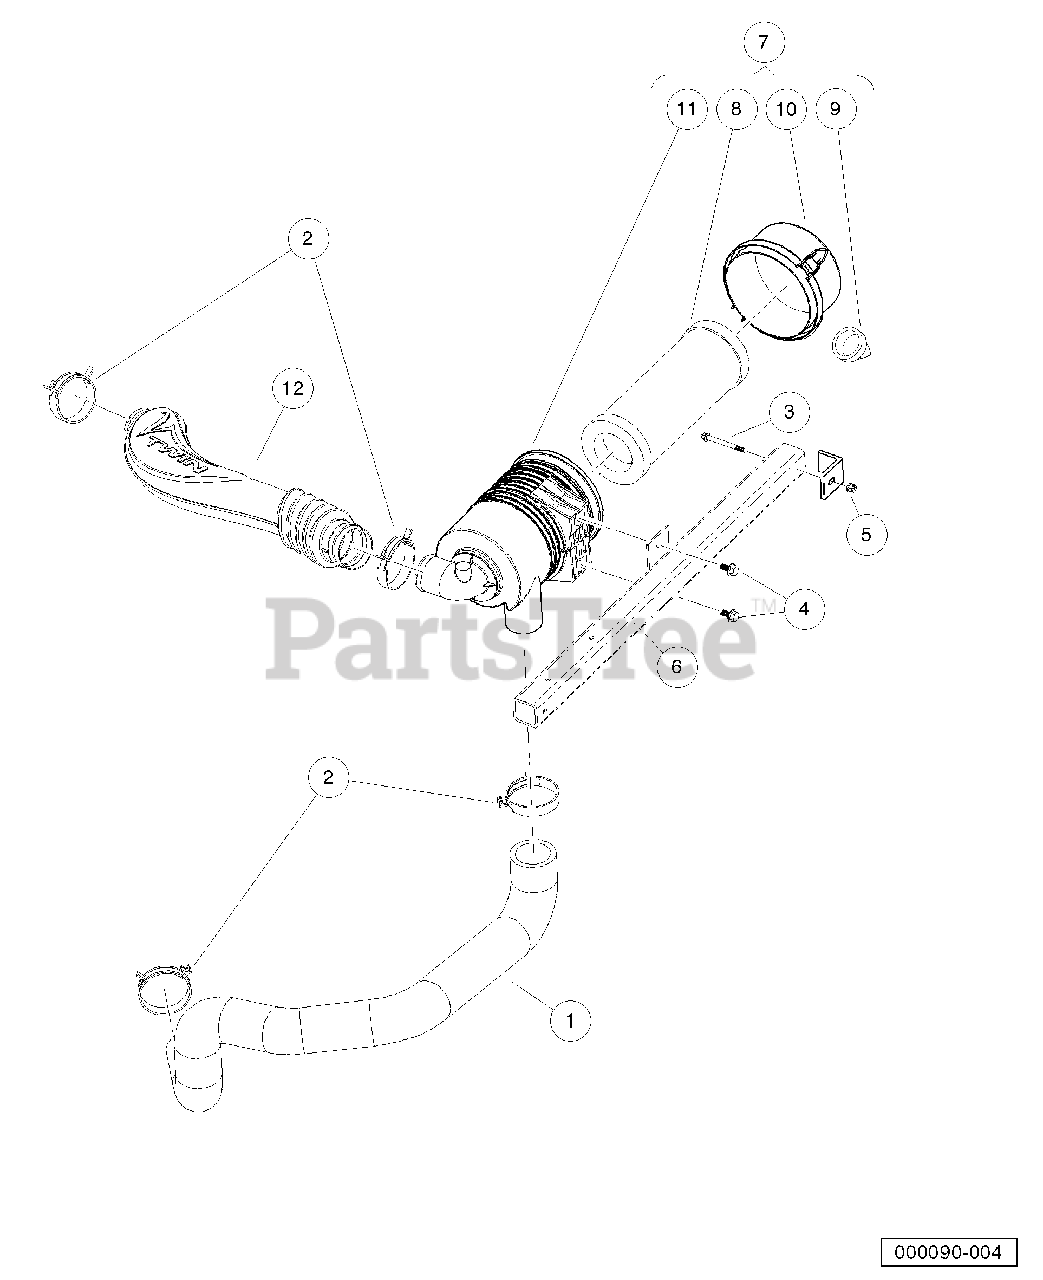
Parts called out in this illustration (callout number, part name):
1	Hose, Intake, Primary
2	Clamp, Hose, Ctb 64mm
3	Bolt, M 6 X 1.0 X 65 Hex, Flange, Head, Black
4	Bolt Flanged Head, M8 X1.25x 16 with Loctite
5	Nut Flg, M6 X 1.0 Nylon
6	Weldment, Support, Air Cleaner
7	Filter, Air, Canister, W/labe
8	Element, Filter, Air, 5 In
9	Valve, Evacuator, Filter Air
10	Cap, Latch Lock, Filter, Air
11	Body, Canister, Filter, Air
12	Hose, Intake, Fh680d
